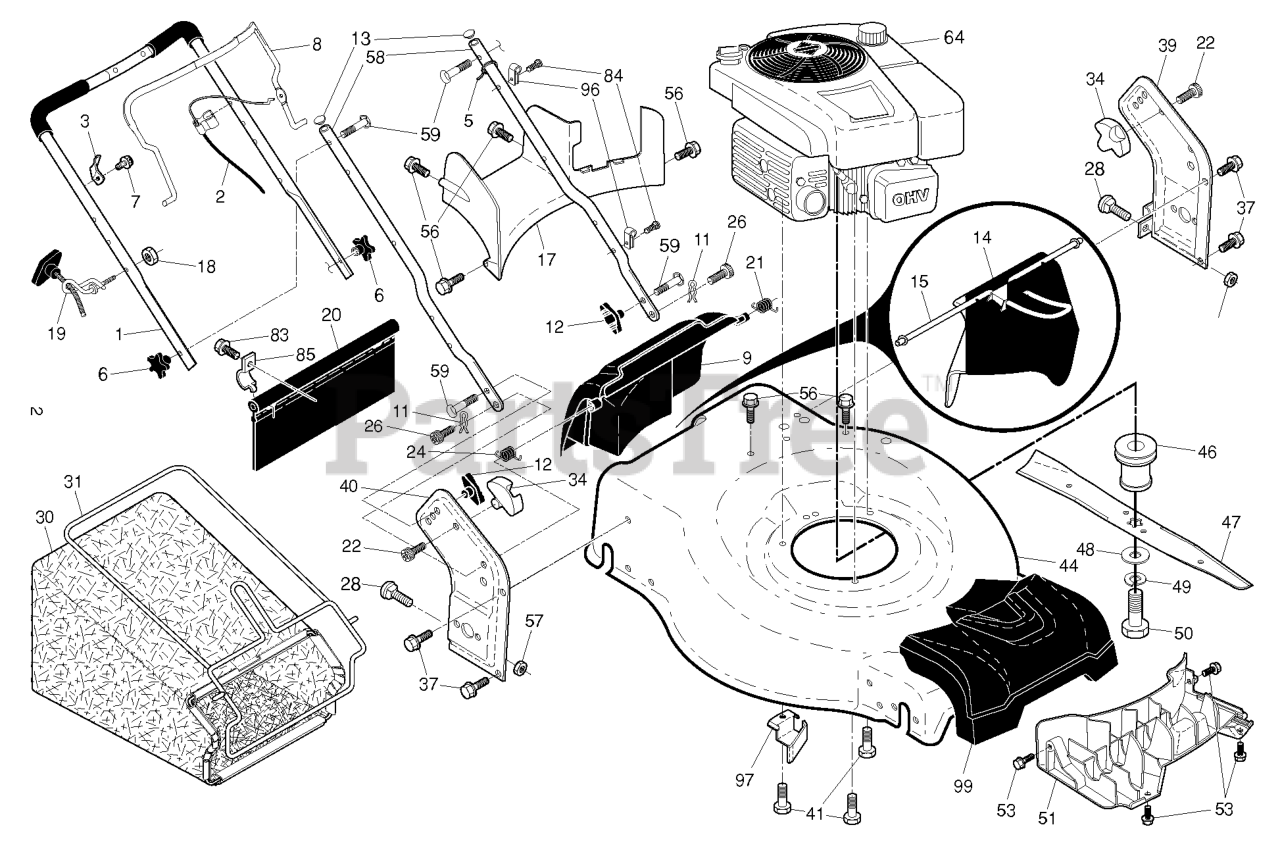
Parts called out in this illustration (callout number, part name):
1	HANDLE.ASM.UP.BS.AW2.GRIP.498
2	CABLE.MZR.50.SNAP-IN
3	BRACKET.UPSTOP.RT
6	KNOB.HANDLE.PLASTIC.STAR.BLACK
8	BAIL.CONTROL.MZR.BS.ORANGE
9	DOOR.REAR.ASM.22+.HUSQ.FG/RGD
11	COTTER.HAIRPIN.DOOR/HANDLE.PIV
12	KNOB, DEFLECTOR
13	PLUG.PLASTIC.7/8".14-20.GAUGE
14	DEFLECTOR.CHUTE.22+REAR
15	HANDLE DEFLECTOR.22+REAR
17	BAFFLE.REAR.22+RGD.AWD.PLASTIC
18	NUT
19	RB GUIDE.ROPE.STD.BLK.ZIN WSL
20	SKIRT.REAR.22+RGD.HIGH WHEEL
21	SPRING.LH.BLACK
22	SCREW.PAN.HEAD.#10
24	SPRING.RH.GRAY
26	SCREW,DOOR/HANDLE.PIVOT
28	BOLT
30	GBAG.A3610247T.SILV.HUSWT.BLUE
31	RB FRAME.GBAG.22PLUS
34	BRACKET.GRASSBAG.ATTACHING.BLK
37	BOLT.5/16HEX.WHS.HD
39	BRACKET.ASM.HNDL.RT.22+.GREY
40	BRACKET.ASM.HNDL.LT.22+.GREY
41	BOLT 3/8-16X1-1/8
44	HOUSING.22+.RWD.HD.WO/PORT.ORN
46	ADAPTER.BLADE.25MM.3MPH
47	BLADE.22+.PREMIUM/PREC.FGD/RGD
48	WASHER,HARDEN
49	LOCKWASHER
50	SCREW, HEX HD 3/8-24 X 1-3/8
51	BAFFLE.FRONT.22+PLASTIC.(2 2)
53	SCREW.HI-LO.5/16 X.75
56	SCREW.HX.13X.750
57	NUT.FLANGE.5/16
58	HANDLE.LOWER.22+BT.2PC.GRY
59	BOLT, HANDLE 5/16-18X1.75
83	TAPPING SCREW
84	FASTENER.PUSH.O.250X0.783
85	BRACKET.SKIRT.22+.BZP
96	CLIP.CABLE.BLK
97	BRACKET.BELT.GUIDE.22+.BZP
99	COVER.ASM.FRONT.SHROUD.HUSQ.
